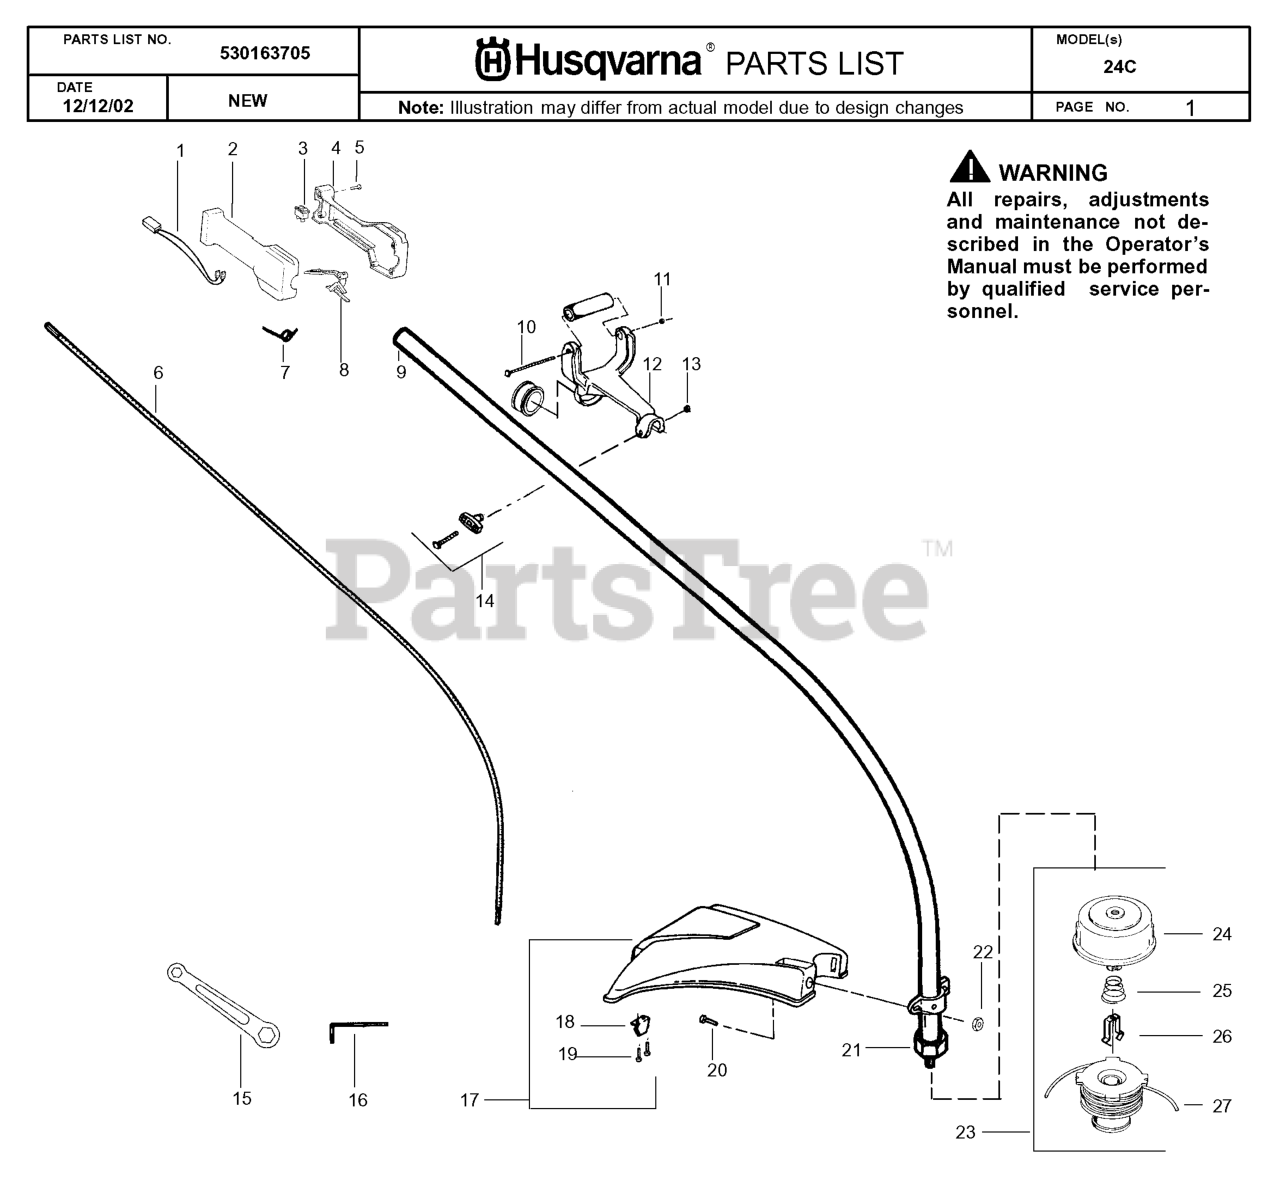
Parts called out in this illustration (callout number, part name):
2	THROTTLE HSG RH GRAY
4	THROTTLE HSG LEFT GRAY
5	SCREW-10-14 X 13/16 (PL
6	SHAFT-FLEX (48")
7	SPRING-LEVER RETURN
8	THROTTLE TRIGGER
9	ASSY D'SHAFT 51"
10	SCREW-12-24 X 4-11/16 P
11	NUT-12-24 (HEX)
12	ANTIVIBE HANDLE
14	HANDLE KIT
16	HEX WRENCH 5/32
18	Limiter - Line
20	BOLT, TYPE 2
21	DUST PROTECTION
24	KIT ASSY HUB W/ARBOR
27	WOUND SPOOL ASSY .080 x 2
530163627	MANUAL OPERATORS SCAN
530163628	MANUAL OPERATORS EURO
530163630	MANUAL OPERATORS EURO III
